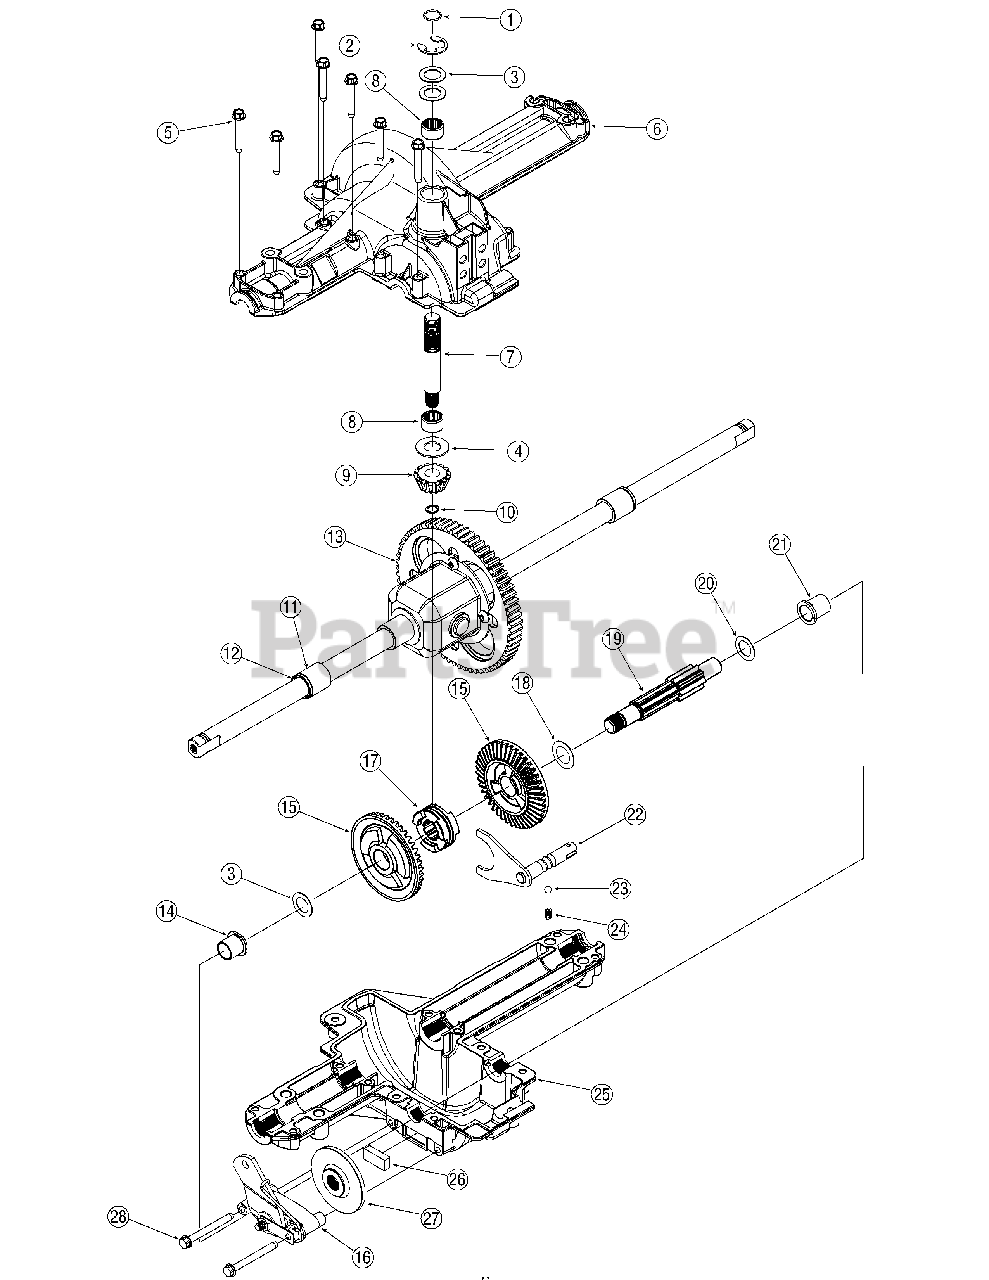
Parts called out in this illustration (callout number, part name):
1	Ring, Wire
2	Ring, E Type, .750
3	Flat Washer, 5/8 x 1.0 x .030
4	Washer, Thrust .635 x 1.26 x .06
5	Self-tapping Screw, 1/4-20 x 1.625
6	Upper Housing
7	Input Shaft
8	Needle Bearing, .625 x .813 x .495
9	14-tooth Bevel Pinion
10	Retaining Ring, .437
11	Sleeve Bearing, .75 x .1.0 x 1.0
12	Seal, .75 x 1.0 x .125
13	Differential Assembly
14	Flange Bearing, 5/8 x 3/4 x 3/4
15	42-tooth Bevel Gear
16	Brake Assembly
17	Clutch Collar
18	Flat Washer, .70 x 1.125 x .031
19	Drive Shaft
20	Thrust Washer, 1.0 x .632 x .0
21	Flange Bearing, 5/8 x 3/4 x 15/16
22	Detent Shaft Assembly
23	Detent Ball
24	Compression Spring
25	Lower Housing
26	Brake Puck
27	Brake Disc
28	Self-tapping Screw, 1/4-20 x 2.375
